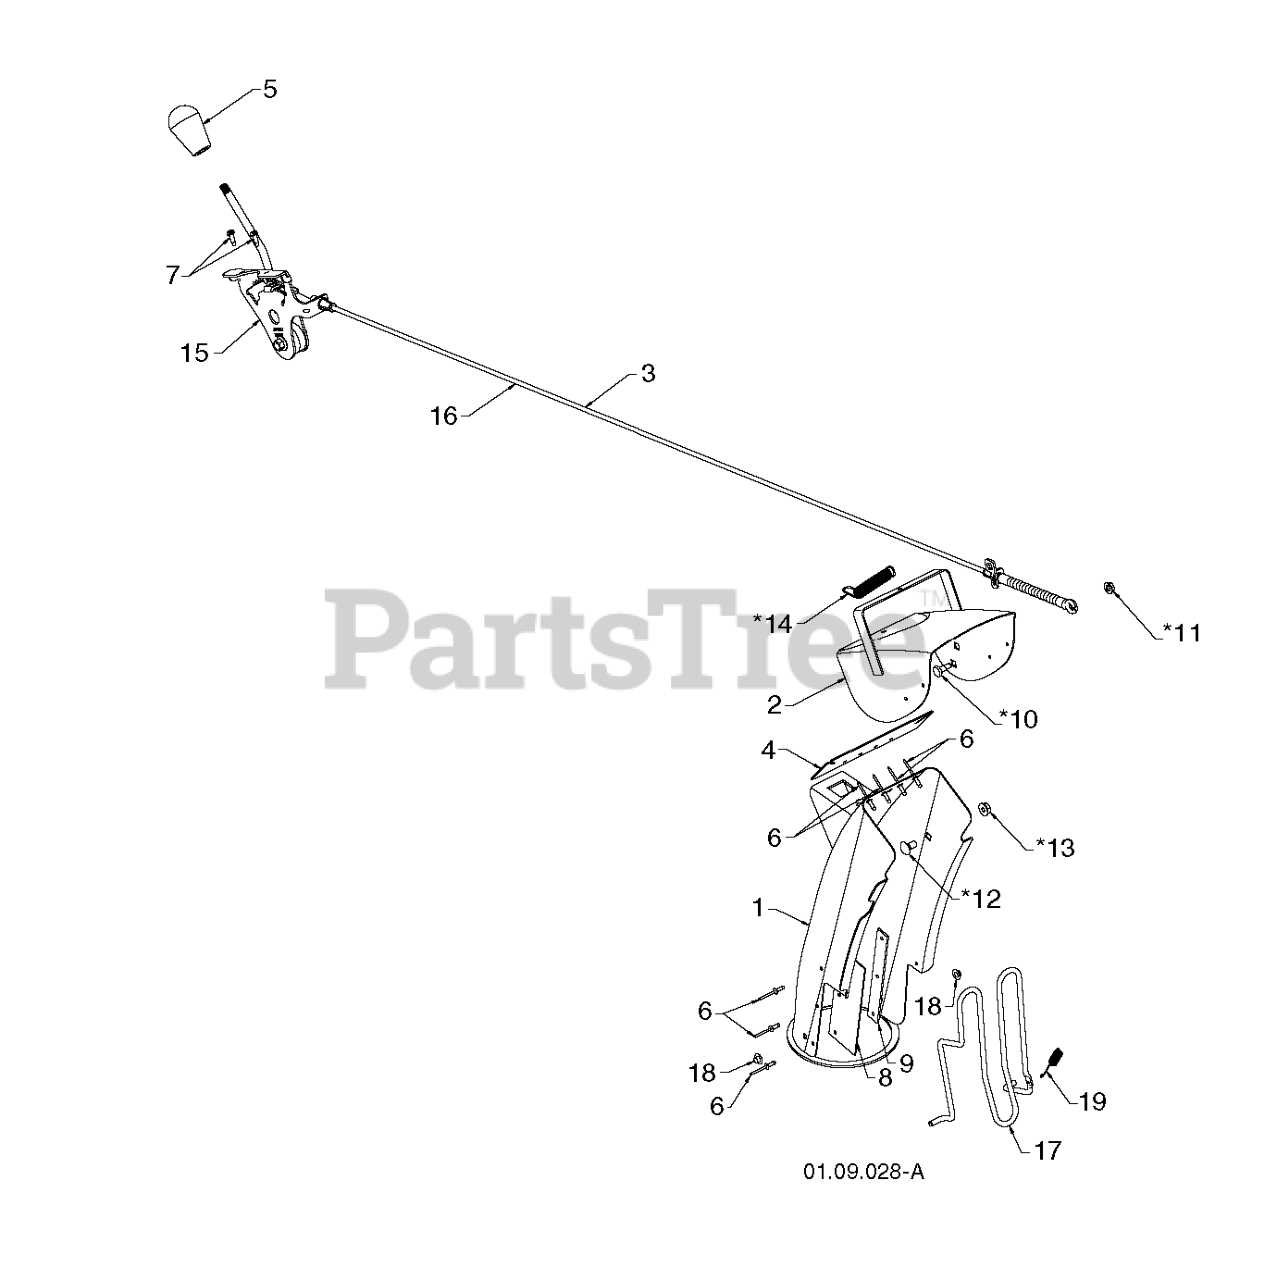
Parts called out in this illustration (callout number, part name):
1	CHUTE.WELDMENT.SNOW.ORANGE
2	DEFLECTOR.WELDMENT.PNT.ORANGE
3	RP.CONTROL.ASM.DEFLECTOR.SNOW
4	SEAL.DEFLECTOR
5	KNOB LEVER, BLACK
6	RIVET BLIND
7	SCREW #10-24 X 5/8
8	SHIELD.SNOW.CHUTE
9	STRAP.SHEILD.RETAINER
10	BOLT, SHOULDER
11	NUT.HEX.FLANGE.1/4
12	BOLT
13	NUT.LOCK.5/16-18
14	SPRING.DEFLECTOR.REM.CHUTE
15	RP CNTRL.HEAD.ASSEM.DEFLECTOR
16	RB SERVICE.CHUTE.DEF.CBL.BLK
17	ROD.GUARD.CHUTE (2 2)
18	NUT
19	SPRING.CHUTE.GUARD
